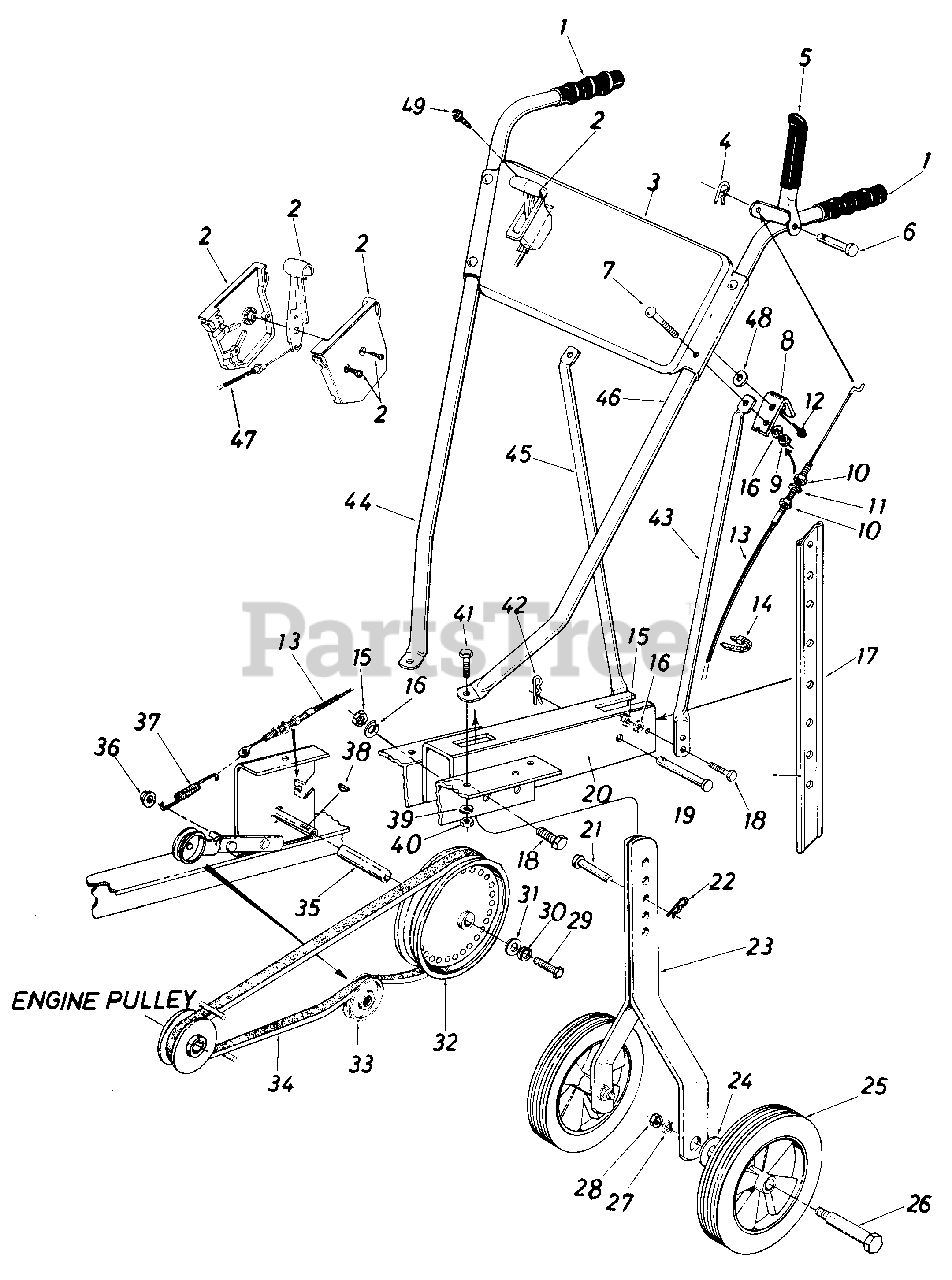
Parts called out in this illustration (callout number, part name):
2	Throttle Control Box
3	Handle Panel
4	Int. Coter Pin
5	Clutch Grip Ass'y.
6	Clevis Pin
7	Carriage Bolt 5/16-18 x 1.75" Lg.\
8	Cable Support Brkt.
9	Hex Nut 5/16-18 Thd.
10	Hex Jam Nut 5/16-24 Thd.
11	L-Wash. 5/16" I.D.
12	Hex Wash. Hd. Self-Tap Scr. 1/4-20 x .50" Lg.
13	Clutch Control Cable
14	Cable Tie
15	Hex Nut 5/16-18 Thd.
16	L-Wash. 5/16" I.D.
17	Depth Bar
18	Hex Bolt 5/16-18 x .75" Lg.
19	Clevis Pin 1/2" Dia. x 2.50" Lg.
20	Tailpiece Ass'y.
21	Clevis Pin 3/8" Dia. x 2.50" Lg.
22	Hairpin Coter
23	Wheel Bracket Ass'y.
24	Belleville Wash. 1/2" I.D.
25	Wheel Ass'y. 9 x 1.75
26	Shoulder Bolt
27	L-Wash. 1/2" I.D.
28	Hex Nut 1/2-20 Thd.
29	Hex Bolt 1/4-28 x .75" Lg.
30	L-Wash. 1/4" I.D.
31	Fl-Wash. .25" I.D. x .930" O.D.
32	Pulley 6.00" O.D.
33	Idler Pulley
34	"V"-Belt 1/2" Pitch x 39" Lg.
35	Spacer
36	Cap Speed Nut
37	Extension Spring
38	Hi-Pro Key
39	L-Wash. 5/16" I.D.
40	Hex Nut 5/16-18 Thd.
41	Hex Bolt 5/16-18 x .75" Lg.
42	Hairpin Coter
43	Handle Support Bracket- L.H.
44	Handle Bar-R.H.
45	Handle Support Bracket- R.H.
46	Handle Bar-L.H.
47	Throttle Control Cable-35"
48	Fl-Wash. .281" I.D. x .50" O.D.
49	Self-Tap Scr. #10 x 1/2" Lg.
